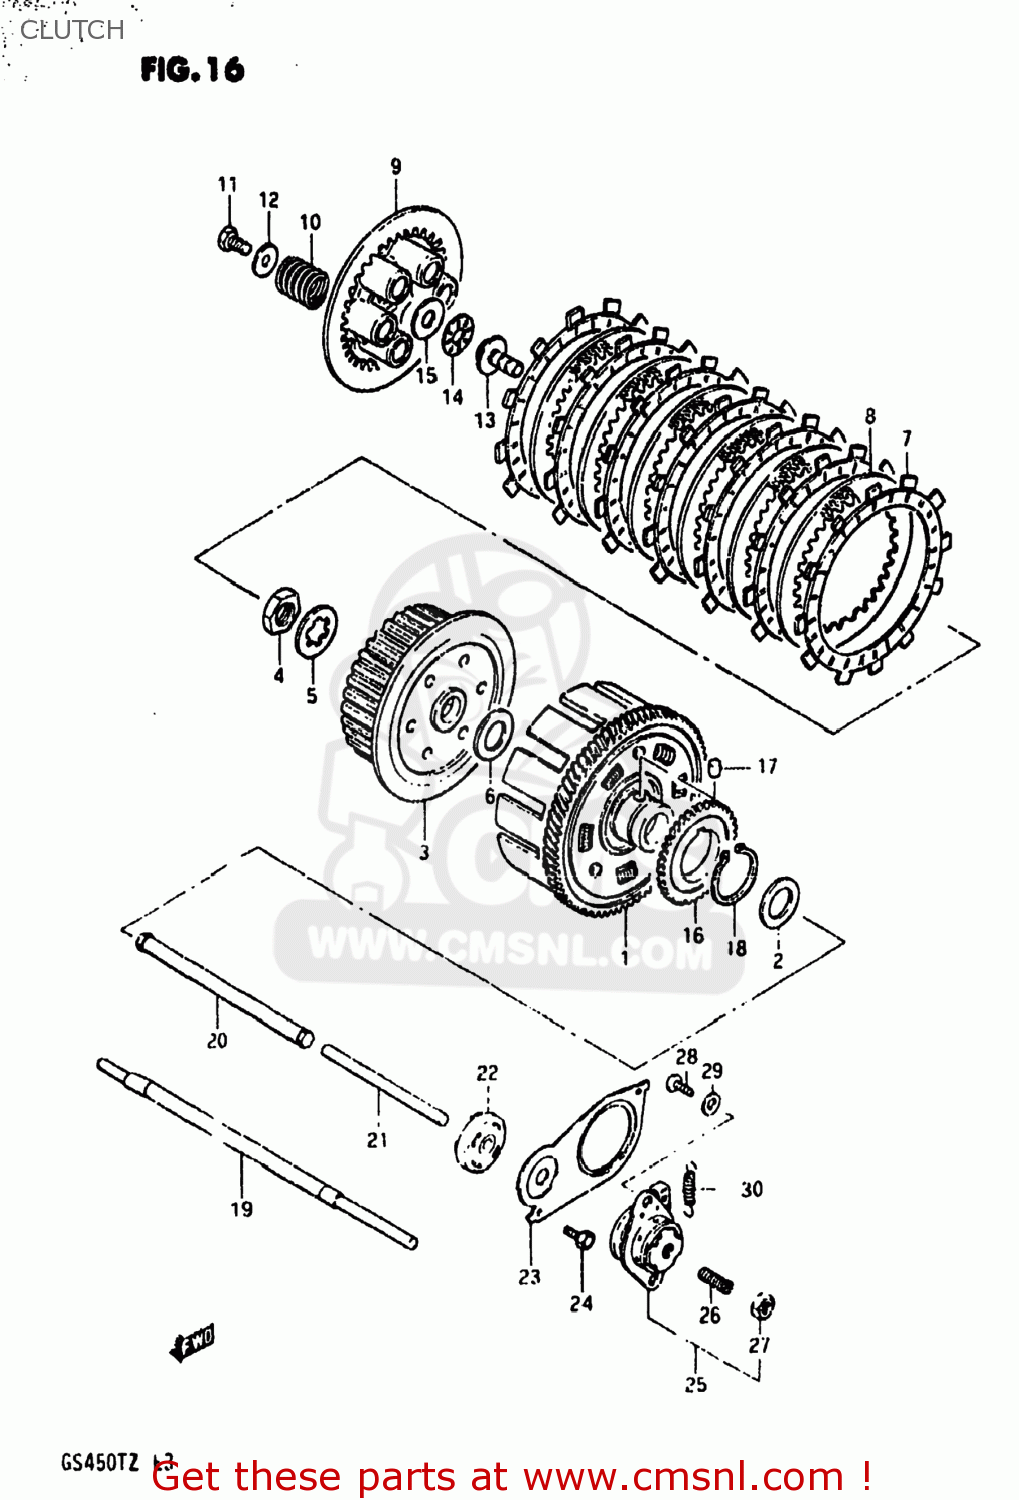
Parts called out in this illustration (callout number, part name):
1	GEAR ASSEMBLY,PRIMARY DRIVE
2	WASHER
3	HUB,CLUTCH SLEEVE
4	NUT (20MM)
5	WASHER,LOCK
6	WASHER(20X44X3)
7	PLATE,CLUTCH DRIVE (MCA)
8	PLATE,CLUTCH DRIVEN (NAS)
9	DISC,CLUTCH PRESSURE
10	SPRING
11	BOLT, UPPER
12	WASHER
13	PIECE,CLUTCH PUSH
14	BEARING(15X28X2)
15	WASHER
16	GEAR,OIL PUMP DRIVE
17	PIN(6X6)
18	CIRCLIP
19	ROD,CLUTCH PUSH
20	ROD,CLUTCH PUSH
21	ROD,CLUTCH PUSH
22	SEAL,OIL(6X34X10)
23	PLATE,CLUTCH PUSH ROD
24	BOLT
25	SCREW ASSEMBLY,CLUTCH RELEASE
26	SCREW
27	NUT 6MM
28	SCREW
29	WASHER
30	SPRING
